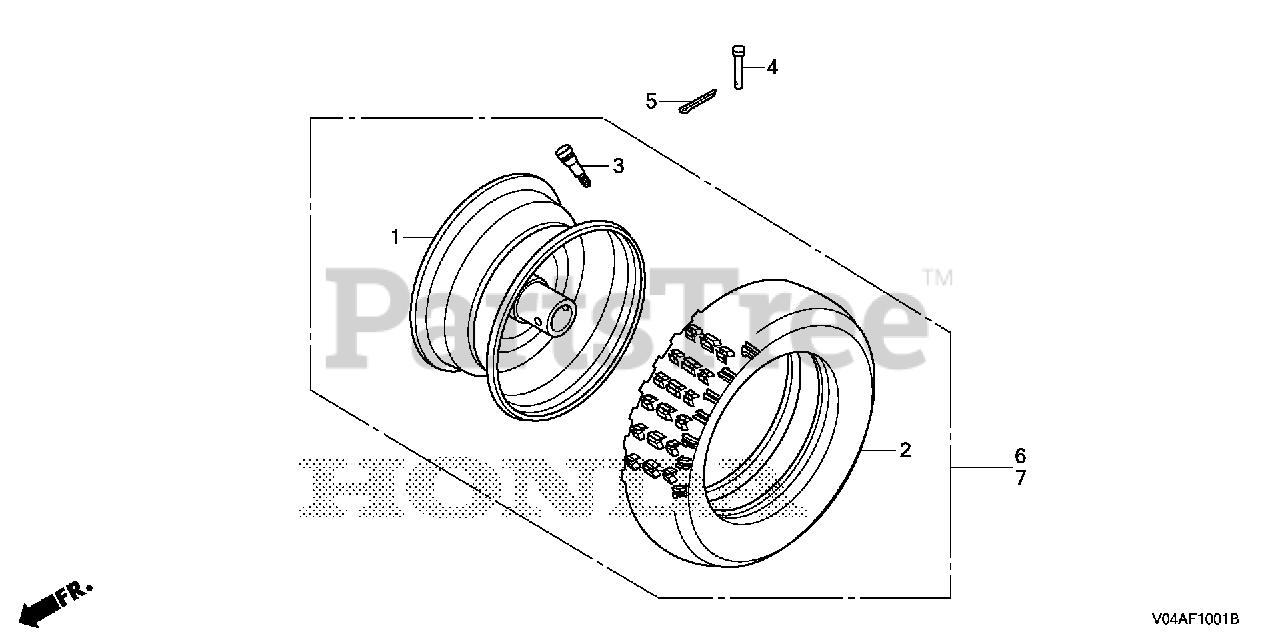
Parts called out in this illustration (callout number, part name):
2	TIRE (15X5.00-6)
3	VALVE, RIM
4	PIN, CLEVIS (6.3X35)
5	PIN, SPLIT (3.0X18)
6	WHEEL ASSY., R. (15X5.00-6)
7	WHEEL ASSY., L. (15X5.00-6)
